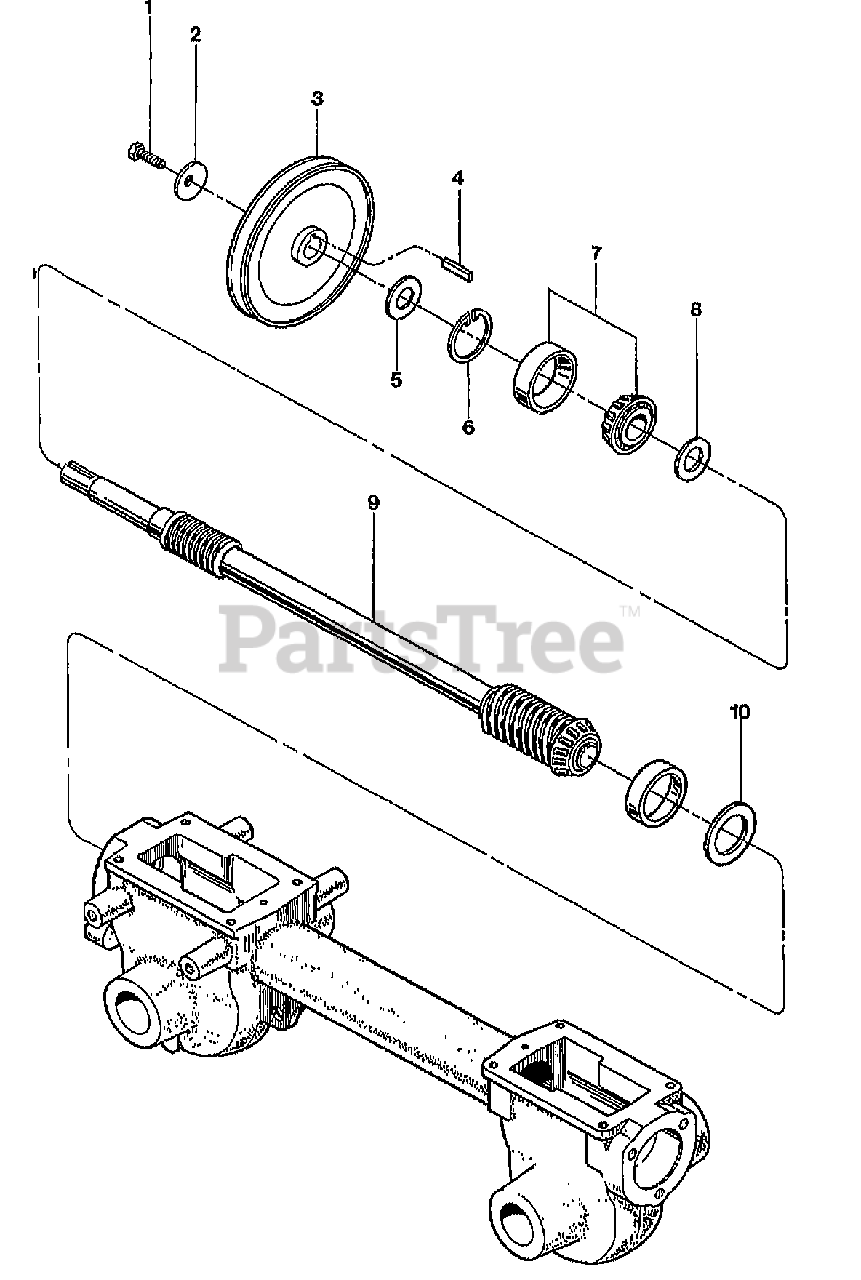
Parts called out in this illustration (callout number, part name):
1	SCR-HH 5/16-24X.75 G5 ZP
2	WASHER-.827X.331X.098
3	PULLEY-TRANSMISSION
4	KEY-.188 SQX1.0
5	WASHER-SHLDR HARDENED
6	RING-RETAINING 5000-181
7	KIT-BRG CONE&RACE-DRIVESHAFT
8	WASHER-#1.25X.75X.06
9	DRIVESHAFT-MACH
9	ASSM-DRIVESHAFT TUFFY {12155}
10	SHIM-1.75X1.5X.01 AS REQ'D
10	SHIM-1.75X1.5X.03 AS REQ'D
10	SHIM-1.75X1.5X.005 AS REQ'D
10	SHIM-1.75X1.5X.062 AS REQ'D
10	SHIM SET-DRIVESHAFT-HORSE
